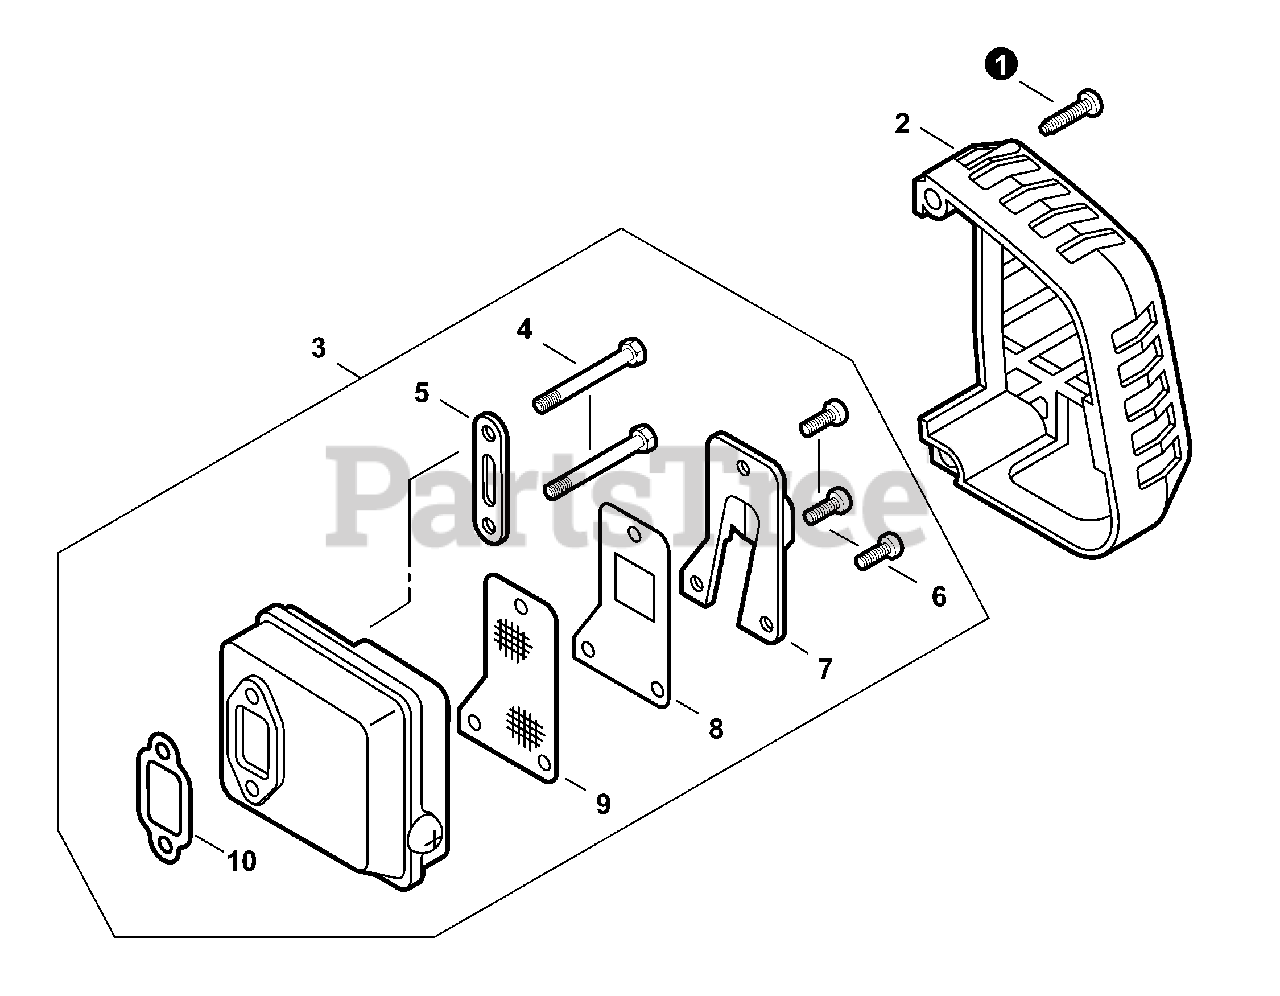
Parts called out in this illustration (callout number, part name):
1	SCREW, TAPPING 5×20
2	COVER, MUFFLER
3	MUFFLER ASSY
4	BOLT, FLANGE HSH 5×45
5	PLATE, EYE
6	SCREW 4×10
7	COVER, MUFFLER
8	GASKET, EXHAUST
9	SCREEN, SPARK ARRESTER
10	GASKET, MUFFLER
